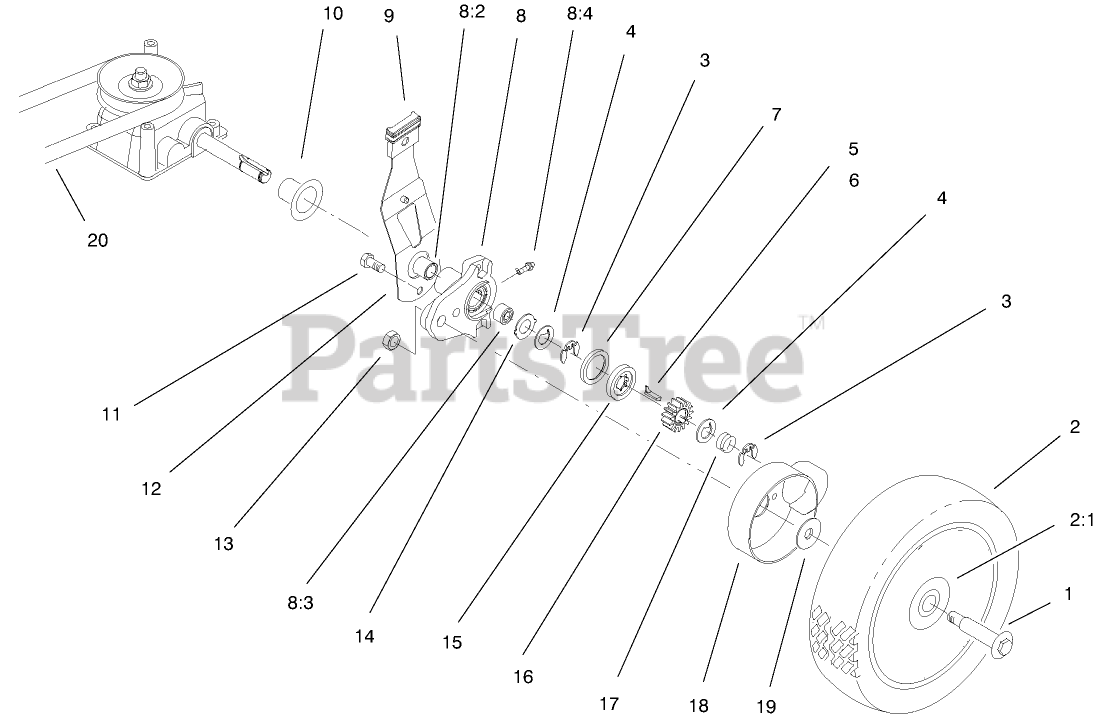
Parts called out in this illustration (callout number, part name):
1	BOLT-SHOULDER
2	WHEEL TIRE ASM (SP)
2:3	Wheel ASM
2:3:1	BUSHING
3	RING-RETAINING,CLIP
4	WASHER-THRUST, KEYED
5	KEY-ROCKING, RH
6	KEY-ROCKING, LH
7	RING-FRICTION
8	PIVOT ARM ASM
8:2	BUSHING
8:3	BUSHING
8:4	FITTING-GREASE
9	KNOB-ARM
10	CAP-END
11	SCREW-HWH
12	SPRING ARM ASM
13	LOCKNUT
14	WASHER-ARM, PIVOT
15	WASHER-CLUTCH
16	GEAR-PINION
17	SPRING-COMPRESSION
18	COVER-WHEEL
19	SPACER-COVER, WHEEL
20	BELT-V
